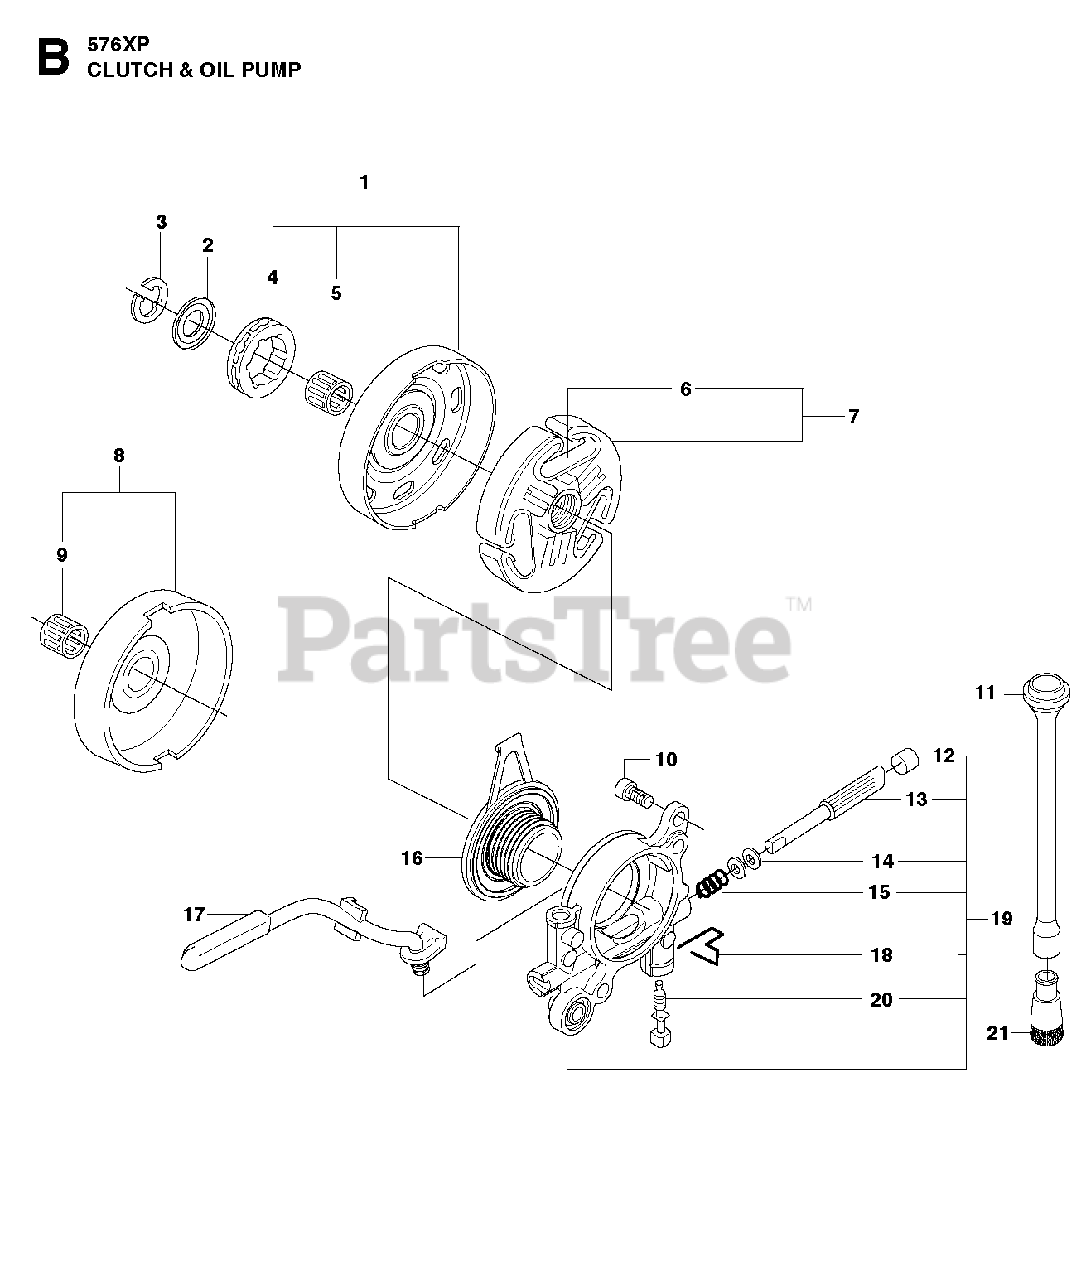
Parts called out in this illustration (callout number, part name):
1	CLUTCH DRUM ASSY
3	RETAINING RING
4	68210 RIMSPROCKET
4	Power Mate Rim
5	CLUTCH DRUM BEARING
6	SPRING
7	CLUTCH
8	CLUTCH DRUM
9	CLUTCH DRUM BEARING
12	PLUG
13	PUMP PISTON
14	WASHER 6.1X9
15	SPRING
16	PINION
18	SPRING CLIP
19	OIL PUMP
20	SCREW
21	OIL SCREEN
